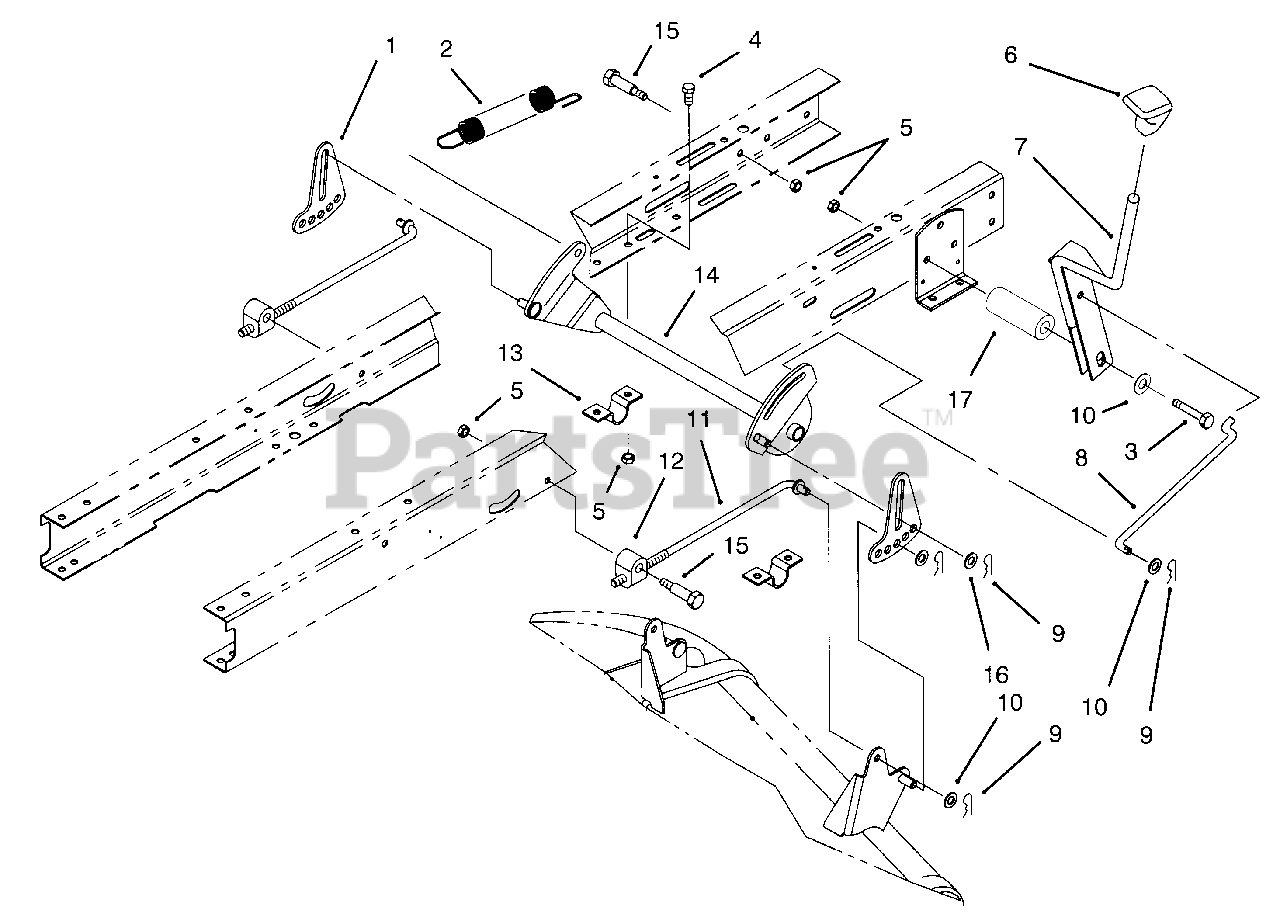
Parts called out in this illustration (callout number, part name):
1	Link-Adjusting H.O.C.
2	Spring-Extension
3	Screw-Hex Hd. Cap
4	Screw-Hex Hd. Cap
5	Nut-Lock
6	Knob-Shift
7	Lever-H.O.C.
8	Link-H.O.C.
9	Pin-Hair Cotter
10	Washer-FLat
11	Rod-Hanger Rear
12	Trunnion-H.O.C. Rear
13	Clamp-H.O.C. Pivot
14	Pivot-H.O.C.
15	Bolt-Shoulder
16	Washer-Hardened
